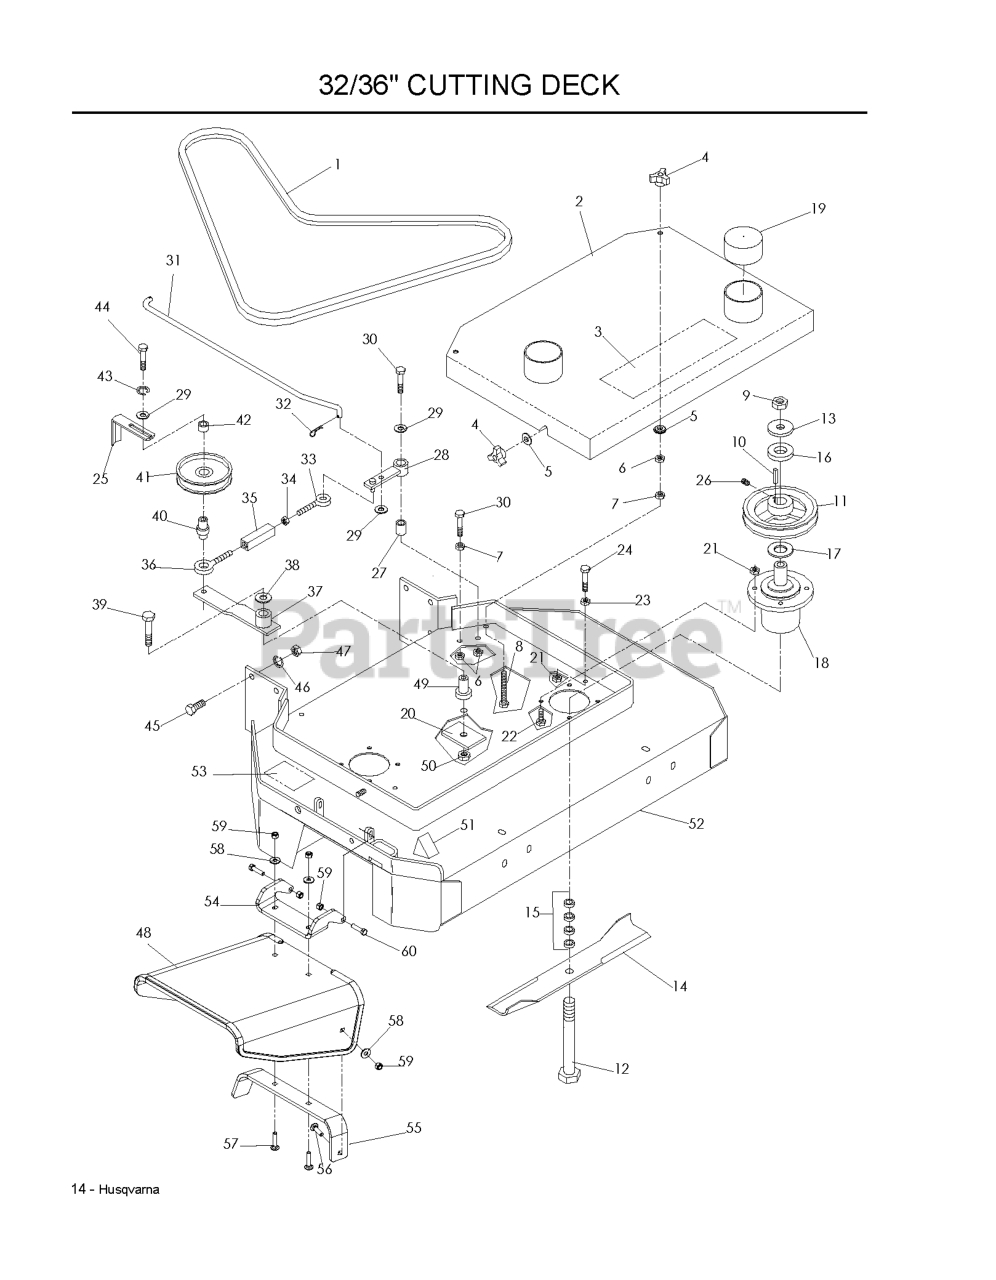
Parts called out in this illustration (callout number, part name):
1	BELT, DECK, 36"
1	BELT, DECK 32"
2	BELT SHIELD 32", ORANGE
2	BELT SHIELD ORANGE 36"
3	DECAL, HUSQ 12" BLUE
4	KNOB, THREE PRONG
5	WASHER, 3/8 SEALING
6	NUT 3/8C CENTERBLOCK
7	NUT 3/8C WHIZ
8	TAPBOLT 3/8C X 4 1/2
9	NUT 5/8F HEX
10	KEY 1/4 SQ X 1 1/8
11	PULLEY W/SETSCREWS
12	HCS 5/8F X 8 1/2
13	WASHER, SUPPORT
14	BLADE OEM 16 1/4"
14	BLADE OEM 18"
15	BLADE SPACERS
17	MACHINERY BUSHING 10 GA.
18	HOUSING ASM
20	PAD
21	NUT 5/16C CENTERLOCK
22	HCS 5/16C X 1
23	NUT 5/16C WHIZ
24	HCS 5/16 X 3
26	SET SCREW 5/16 NYLOC
27	BUSHING, SLEEVE
28	ENGAGEMENT ARM
29	WASHER 3/8 FLAT
30	HCS 3/8C X 2 1/4
31	BLADE ROD 36"
32	HAIRPIN #2
33	EYEBOLT, RH
34	NUT 5/16C HEX
35	TURNBUCKLE
36	EYEBOLT, LH
37	ARM WELDMENT
38	WASHER 1/2 FLAT
39	HCS 1/2C X 2 3/4
40	EYEBOLT PIVOT
41	IDLER PULLEY
43	SLW 3/8 STD
44	HCS 3/8C X 2 1/2
45	HCS 7/16C X 1 1/2
46	WASHER 7/16 LOCK
47	NUT 7/16C HEX
48	CHUTE, RUBBER DISCHARGE WB
49	IDLER SPINDLE
50	NUT 1/2-13 HEX NYLOC ZD
51	DECAL, CPSC
52	DECK W/DECALS 32"
52	DECK W/DECALS 36"
53	DECAL, EURO SEVERING
54	PIVOT BRACKET - CHUTE
55	BRKT, REINF-CHUTE WB
56	BOLT, CARRIAGE 5/16X1-1/4
57	RHSNB 5/16-18 X 1-1/2 GR 5 ZD
58	WASHER 5/16 FLAT
59	NUT 5/16 NYLOC
60	HCS 5/16C X 1 1/4
